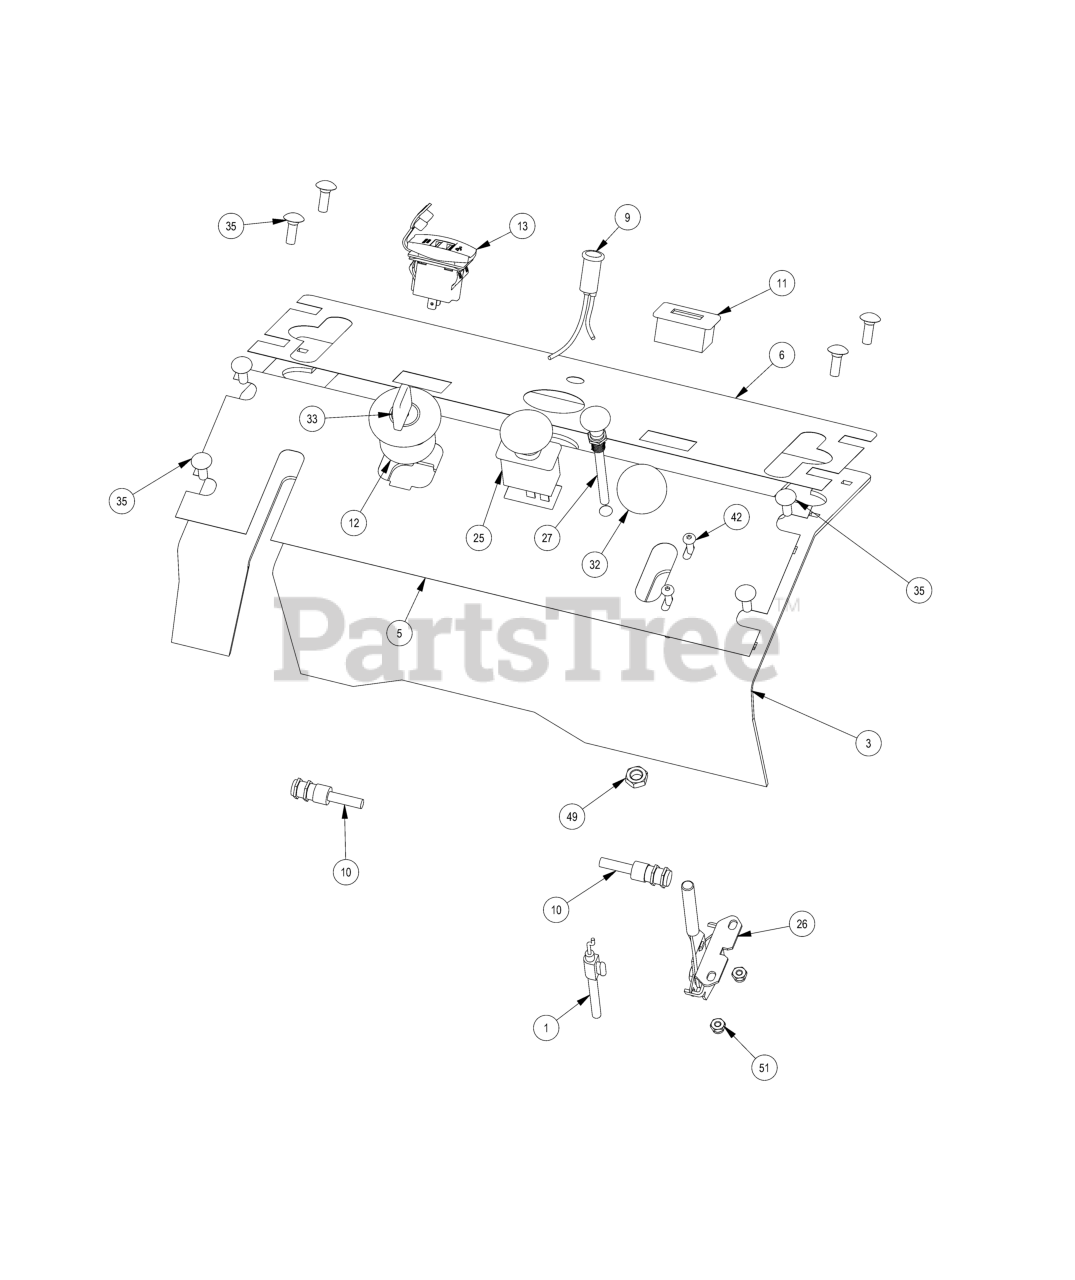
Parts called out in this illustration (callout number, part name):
1	Outlaw Throttle Cable
2	5/16-18 NYLON INSERT JAM LOCKNUT ZINC
3	36" Podium Front Panel Weldment 2020 Stand On
4	2020 36" Hydrotank Carrier Plate 2020 36" Stand On
5	36" Control Panel (lower) - Revolt
6	36" Control Panel (upper) - Revolt
7	2019 Stand On Brake Handle BLACK
8	36" Front Control Arm Stop Weldment 2020 36" Stand On
10	Safety Switch Harness
11	Tachometer
12	Ignition Switch
14	Magnet-Steering Arm-Stand ON
15	2019 Stand On Waterbottle Cage
16	2019 Stand On Control Grip
17	8507A13 McMaster Carr Plunger
18	Interstate FAYTX14 Battery
19	350ml Expansion Tank
20	Hydraulic Tank Cap
21	ZT/Maverick Hydro Tank Hose
22	3/8" Hose Clamp
23	1/2 Hose Clamp
24	Brake Cable
25	PTO Switch
26	Universal Throttle Head - 2012
28	2020 36 Stand On Drive Arm Pivot Bar
29	8-32 HEX M/S NUT ZINC
30	Safety Switch
31	Rubber Brake Grip-cZT/ZT 2013
32	Throttle Knob
33	Ignition Key
34	Brake Spring
35	1/4-20 X 3/4 CARRIAGE BOLT (GR.5) ZINC
36	1/4-20 NYL INSERT FLANGE LOCKNUT ZINC
37	3/8 FLAT WASHER USS (1" OD) ZINC
38	3/8 SPLIT LOCKWASHER ZINC
39	.390 ID X 1.12 OD X .125 THK FLAT WASHER NYLON
40	.390 ID X .750 OD X .062 THK FLAT WASHER NYLON
41	3/8-16 X 1 GR 5 Hex Bolts Zinc
42	10-24 X 5/8 BUTTON SOCKET CAP SCREW 18-8 STAINLESS STEEL
43	3/8-16 X 1-1/4 CARRIAGE BOLT ZINC
44	5/16-18 X 1-1/2 CARRIAGE BOLT ZINC
45	12-24 X 1/2 HEX WASHER UNLSOT F TCS ZINC
46	5/16-18 X 6 CARRIAGE BOLT (GR.5) ZINC
47	M6-1.0 X 16MM DIN 933 HEX TAP BOLT (CL 8.8) ZINC
48	5/16-18 HEX SERRATED FLANGE NUT HARD/ZINC
49	3/8-24 HEX NUT ZINC YELLOW
50	3/8-16 NYLON INSERT FLANGE LOCKNUT (GR.F) ZINC
51	10-24 NYLON INSERT LOCKNUT ZINC
52	5/16-18 X 1 CARRIAGE BOLT (GR.8) ZINC
53	5/16-18 NYLON INSERT FLANGE LOCKNUT ZINC
54	1/4" Vinyl Tubing, 46" Long
55	3/16 Vinyl Clamp
56	3/16" Vinyl Tubing, 55" Long
57	3/16" Vinyl Hose Clamp
58	2023 36-SD Stand On Drive Arm Actuator weldment_left
59	2023 36-SD Stand On Drive Arm Actuator weldment_right
60	2023 Stand on Battery Hold Down
61	Nylon 6 6 Sleeve Washer
62	2023 Podium Panel Left
63	2023 Podium Panel Right
64	MZ Kohler EPA Canister Assembly
65	Expandable Locking Grommets
66	2023 36''/SD Control Arm Stop Weldment_Rear
67	2023 36-SD Stand On Console Bracket Weldment
68	Adjustable handles ERX.30 B-10-24-C1
69	2023 Floor Board Rubber Bumper
70	2019 Revolt Push Rod Assembly
71	ACS Spacer 3/4x3/8x1/4
72	5/16-18 X 1-1/4 HEX C/S (GR.5) ZC
73	2022 36" Revolt Seat Pad
74	5/16 USS FLAT WASHER (7/8 OD) ZINC
75	5/16 SPLIT LOCKWASHER ZINC
76	5/16-18 X 1 HEX CAP SCREW (GR.5) ZINC
77	2023 36-SD Stand on Pad Plate
78	.360 ID Plastic Washer
79	Relay Block Cover Replacement Kit
